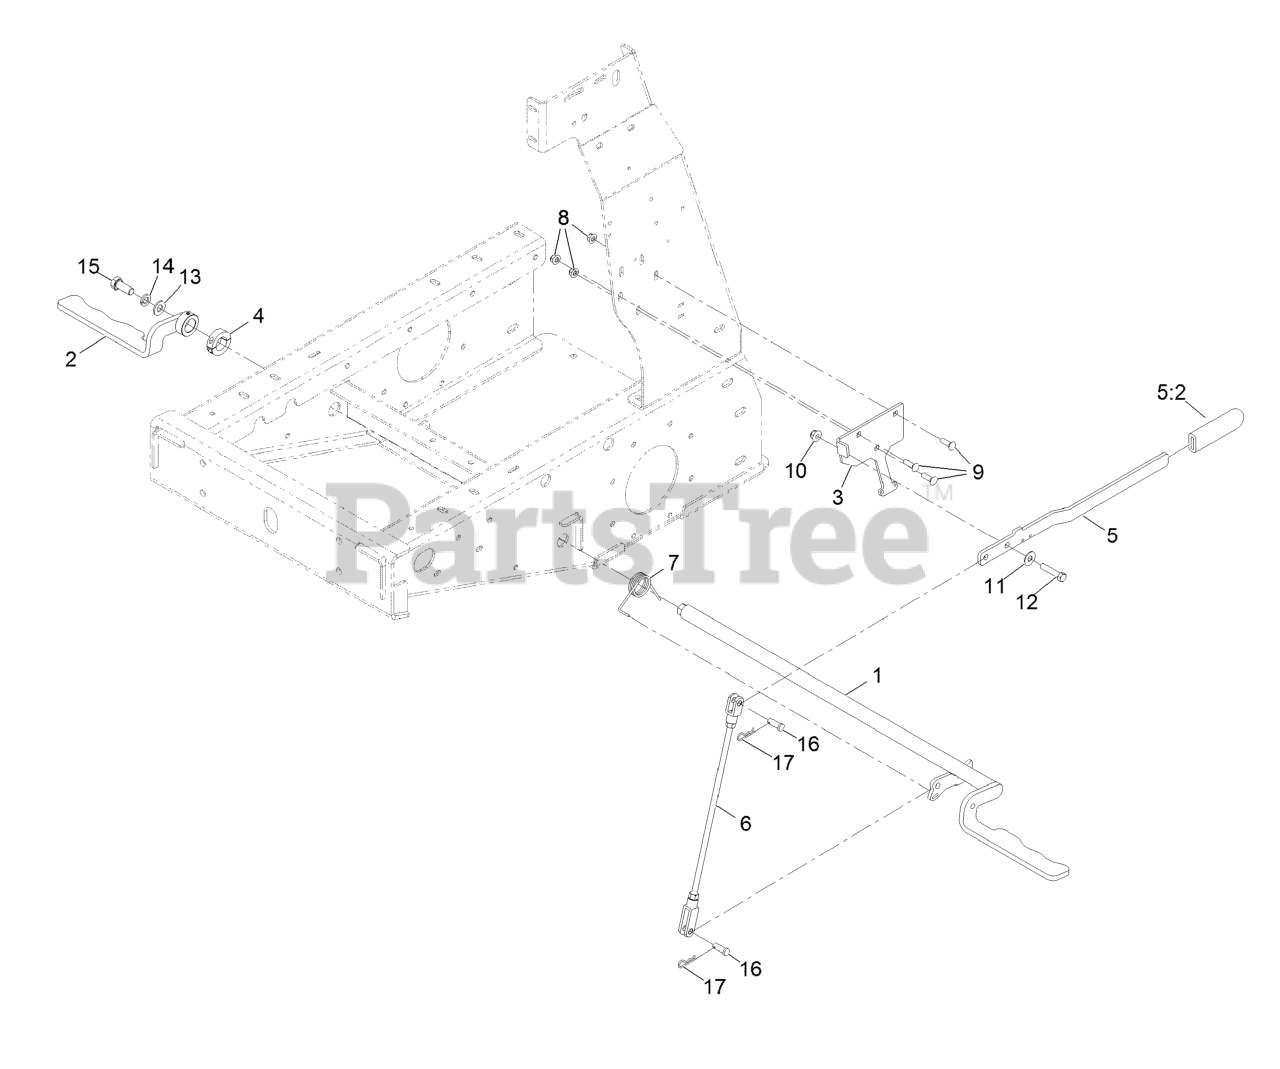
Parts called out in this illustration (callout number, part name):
1	Arm-Brake, Lt [black]
2	Arm-Brake, Rt [black]
3	BRACKET-HANDLE, BRAKE
4	COLLAR-LOCKING
5	ASM, Handle-Brake
5:2	GRIP-LEVER
6	ASM, Rod-Brake
7	SPRING-TORSION
8	Nut-Hex Flange
9	Bolt,Carriage,5/16-18X1,ST/ST 18-8
10	NUT-HF, NI
11	WASHER-FLAT
12	SCREW-HH
13	WASHER-FLAT
14	WASHER-LOCK
15	Screw ( .50-20Unfx1.25 Grade 8]
16	PIN-CLEVIS
17	Pin-Hair
